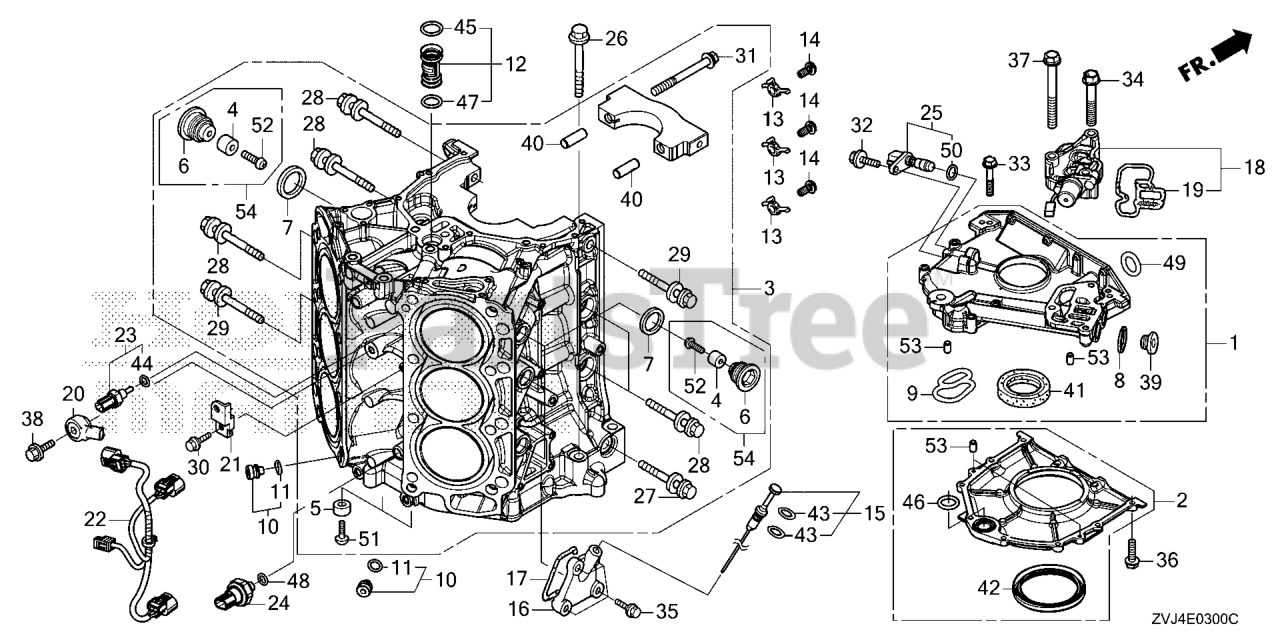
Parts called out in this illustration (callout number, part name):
1	COVER ASSY., CRANKCASE (UPPER)
1	CVR, CRANKCASE
2	CASE ASSY., OIL SEAL
3	BLOCK ASSY., CYLINDER *NH8* (DARK GRAY)
3	BLOCK, CYLN *NH8*
4	METAL, ANODE
5	METAL, ANODE
6	BOLT, SEALING (22MM)
7	WASHER, SEALING (22MM)
8	WASHER, SEALING (22MM)
9	GASKET, OIL HOLE
10	ORIFICE ASSY., OIL CONTROL
11	O-RING (8.8X2.4)
12	JOINT ASSY., OIL PIPE
13	BODY, OIL JET
14	BOLT, OIL JET
15	GAUGE, OIL LEVEL
16	COVER, OIL LEVEL GAUGE
17	GASKET, OIL LEVEL GAUGE
18	VALVE ASSY., SPOOL *NH8* (DARK GRAY)
19	FILTER ASSY., SPOOL VALVE
20	SENSOR, KNOCK
21	BRACKET, CLIP B
22	WIRE, SWITCH
23	SENSOR ASSY., WATER TEMPERATURE
24	SENSOR, OIL PRESSURE
25	SENSOR ASSY., CRANK
26	BOLT, FLANGE (12X95)
27	BOLT-WASHER (10X109)
28	BOLT-WASHER (10X60)
29	BOLT-WASHER (10X80)
30	BOLT, FLANGE (6X14)
31	BOLT-WASHER (11X105)
32	BOLT, FLANGE (6X16)
33	BOLT, FLANGE (6X35)
34	BOLT, FLANGE (8X50)
35	BOLT, FLANGE (6X18)
36	BOLT, FLANGE (6X22)
37	BOLT, FLANGE (8X75)
38	BOLT, FLANGE (8X35)
39	BOLT, SEALING (22MM)
40	PIN, DOWEL (13X37)
41	OIL SEAL (41X66X8)
42	OIL SEAL (80X98X10) (ARAI)
43	O-RING (8.8X1.9)
44	O-RING (9.5X1.9)
45	O-RING (18.3X3.5)
46	O-RING (26.2X2.4) (YAMADA SOMBOON)
47	O-RING (16.3X3.5)
48	O-RING (13X1.5) (ARAI)
49	O-RING (25X2.4) (NOK)
50	O-RING (15X1.9)
51	SCREW, PAN (5X16)
52	SCREW, PAN (5X20)
53	PIN A, DOWEL (6X10)
54	BOLT ASSY., SEALING (22MM)
